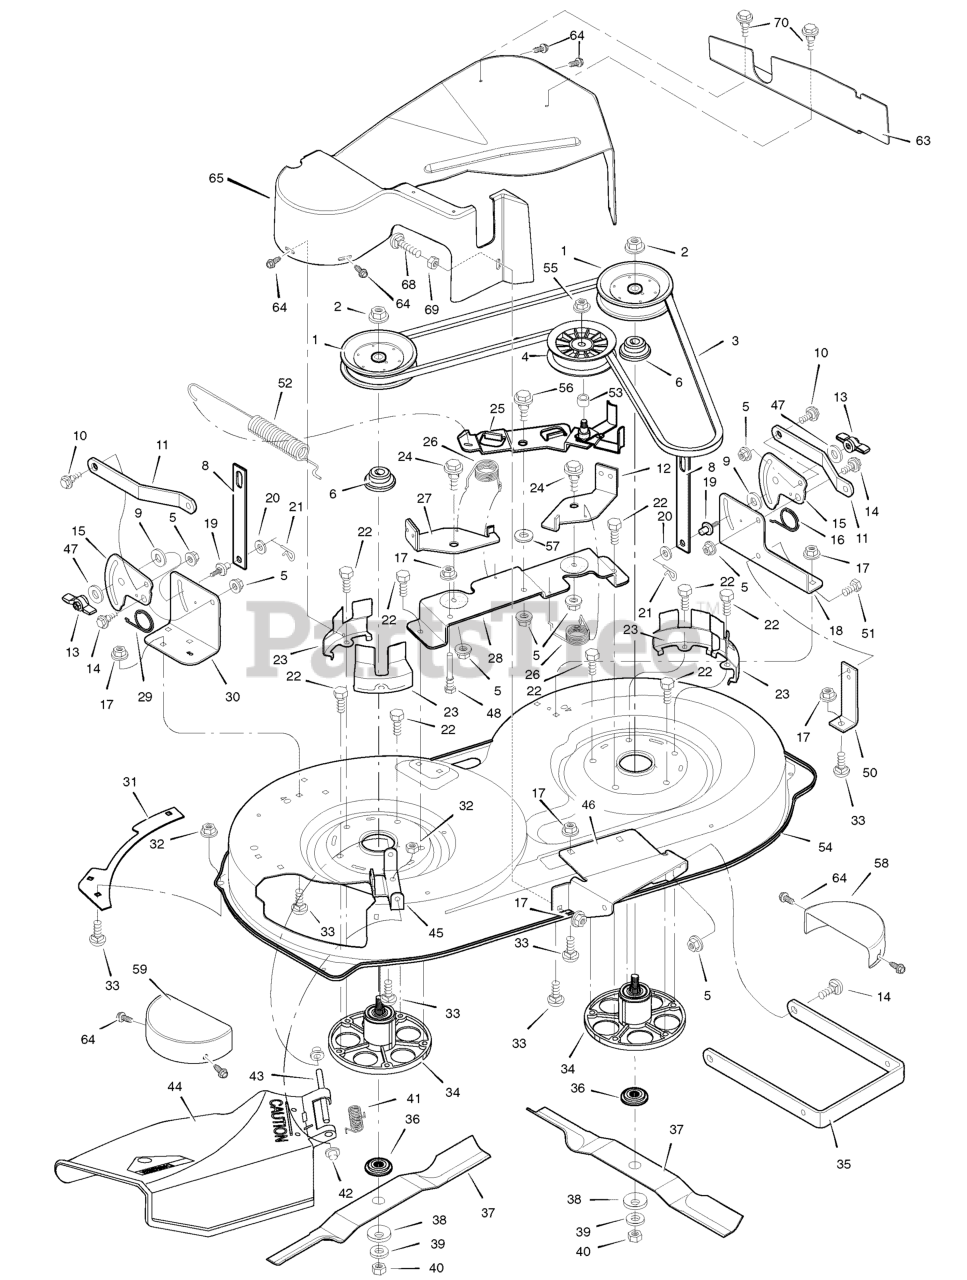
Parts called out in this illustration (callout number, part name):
1	PULLEY, Jackshaft
2	NUT, Hex
3	BELT, Mower Drive
4	PULLEY, Idler
5	NUT, Flange
6	SPACER, Pulley
8	LINK, Lift
9	PAD, Friction
10	BOLT, Shoulder
11	BRACKET, Suspension
12	PAD ASSEMBLY, Left Brake
13	KNOB
14	BOLT, Shoulder
15	PLATE, Suspension
17	NUT, Flange
18	BRACKET, Left Suspension
19	PIN, Hanger
21	PIN, Cotter
23	GUIDE, Belt
24	BOLT, Shoulder
25	ARM, Idler
27	PAD ASSEMBLY, Right Brake
28	BRACKET ASSEMBLY, Brake
30	BRACKET, Right Suspension
32	NUT, Flange
33	BOLT, Carriage
34	MANDRELL
35	BRACKET, Suspension
36	ADAPTER, Blade
37	BLADE
42	CAP, Push On
43	ROD, Deflector
44	DEFLECTOR ASSEMBLY
45	BRACKET, Deflector
46	BRACKET, Front Hanger
48	GUIDE, Belt
50	BRACKET, Support
52	SPRING, Extension
54	HOUSING, Export Blade
55	NUT, Flange
56	BOLT, Shoulder
58	GUARD, Belt L.H.
59	GUARD, Belt R.H.
63	PLATE, Guard 40" LH
65	COVER, Guard
68	BOLT, Carriage, 5/16-18 x 1.50
69	NUT, Hex Lock 3/8-18
70	SCREW HEXHEAD TAP
